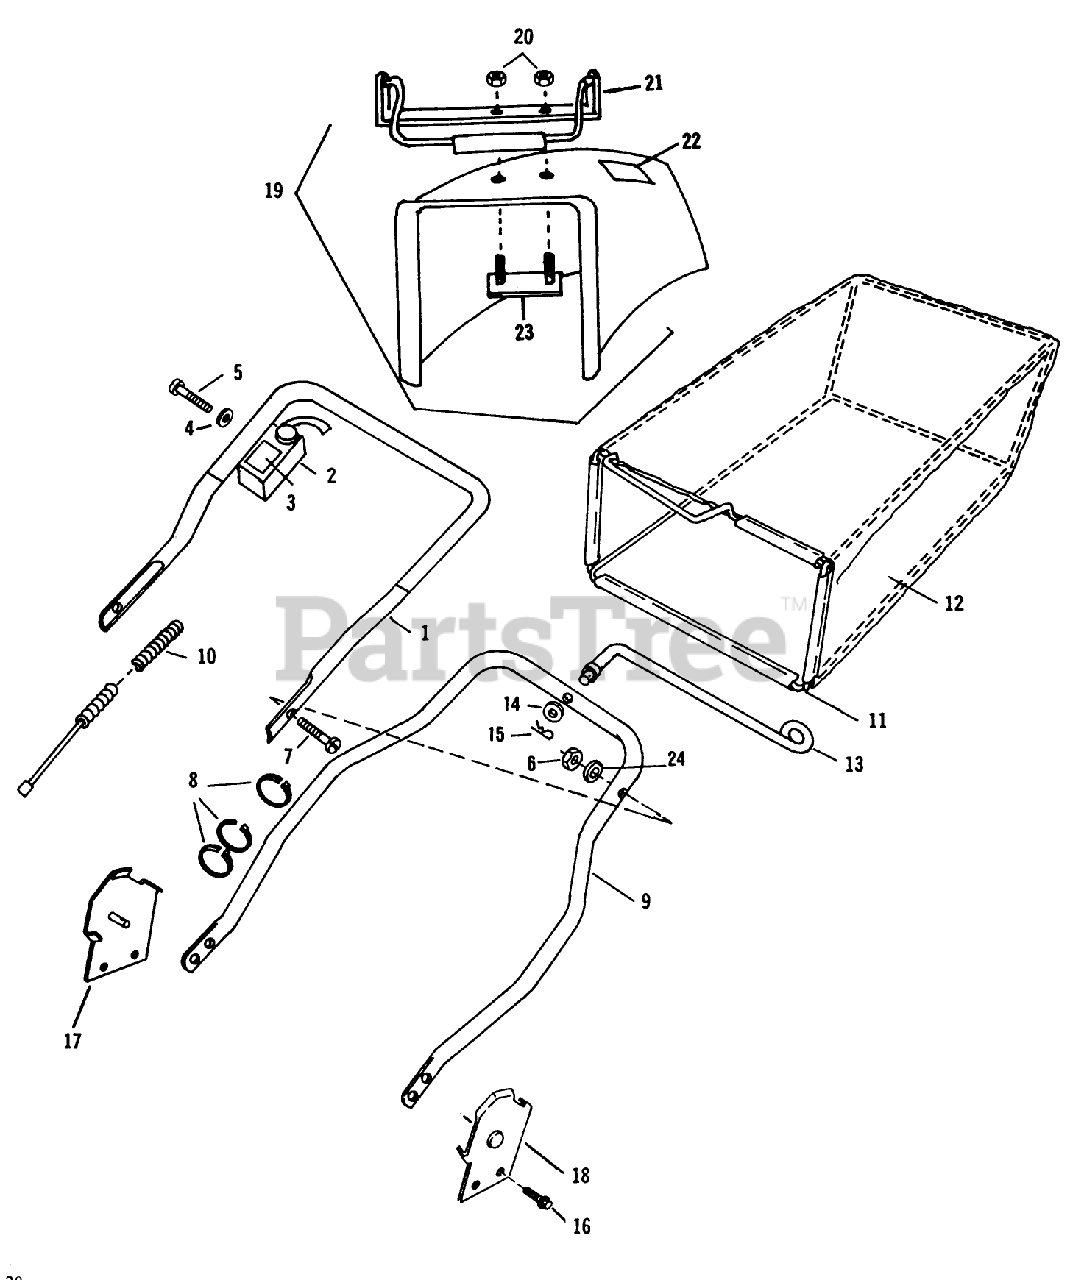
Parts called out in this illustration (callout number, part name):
2	Control Box Ass-y.
4	Insulator-Handle
6	NUT-LOCK F
15	HAIR PIN
18	Handle Brk-t. Ass-y.-L.H.
20	LOCKNUT E
21	LATCH BAR ARGO
24	WASHER-CURVED
